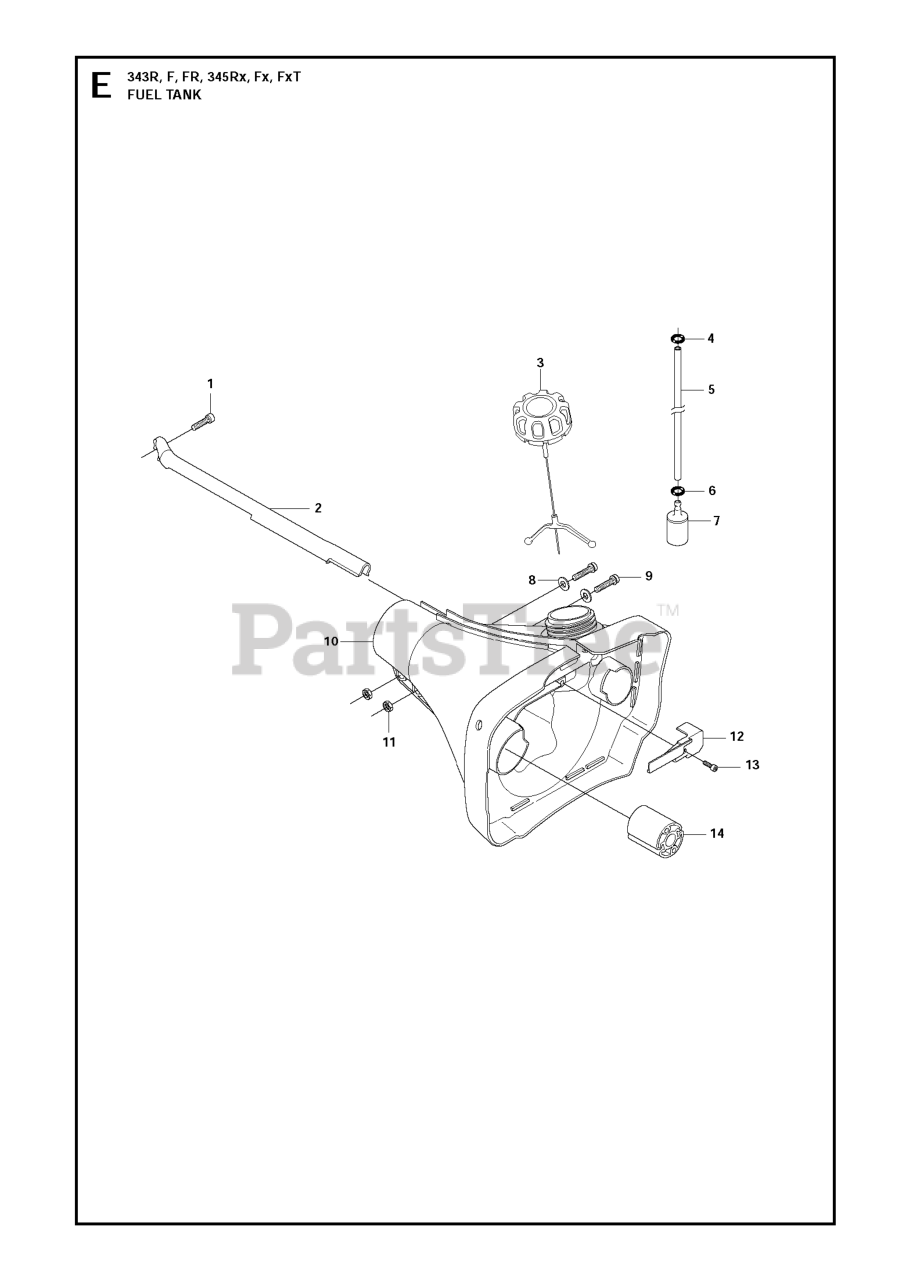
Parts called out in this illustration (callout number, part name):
2	PROTECTOR
3	%WINTER TANK CAP
5	FUEL HOSE
7	RP FUEL FILTER
8	WASHER 5.3X12
10	TANK UNIT
13	SCREW
14	ANTIVIBRATION ELEMENT
